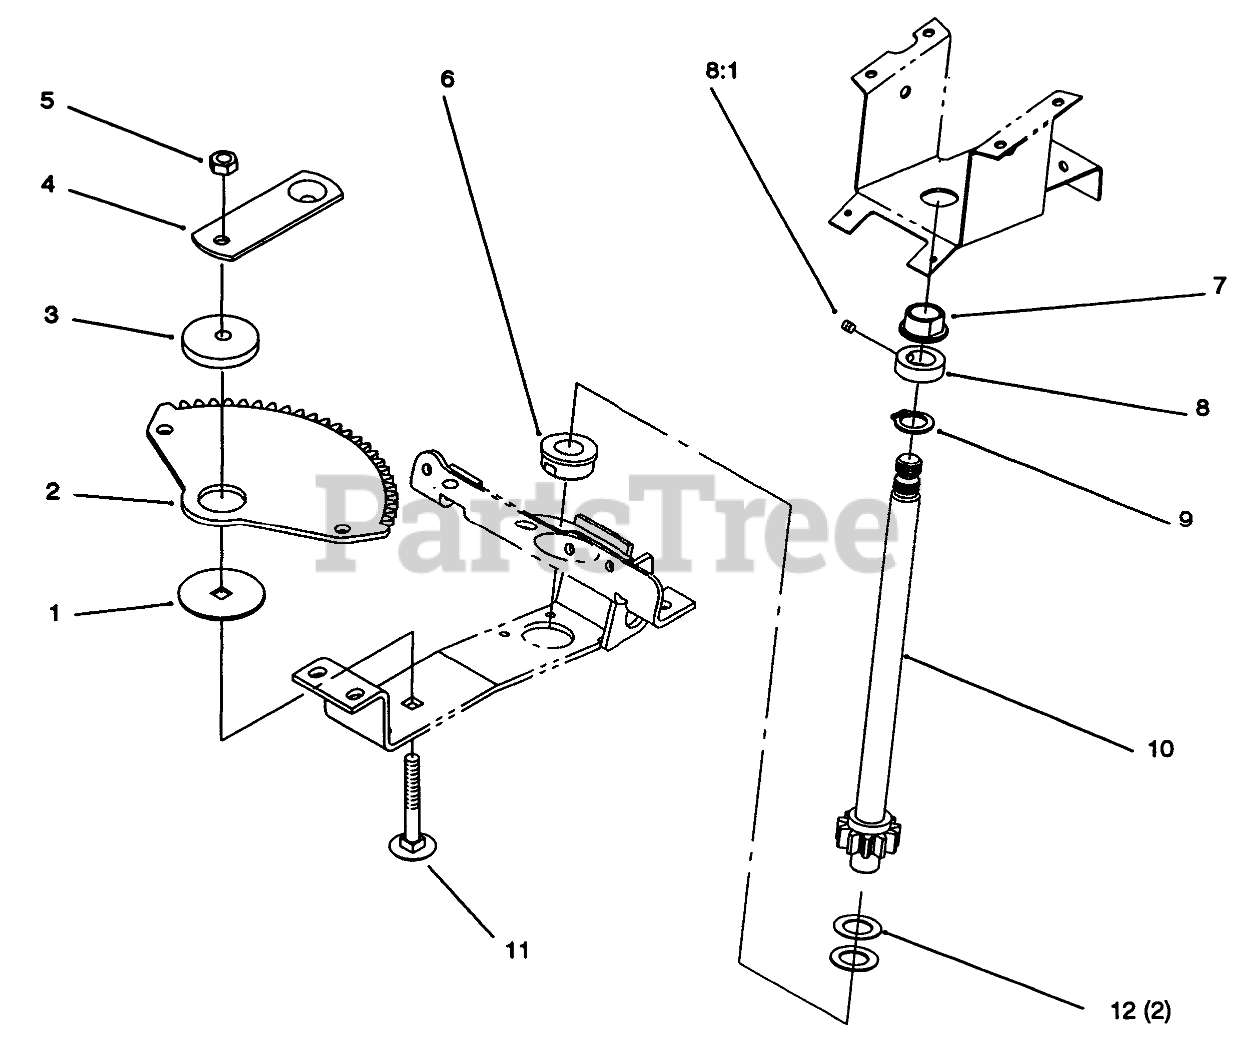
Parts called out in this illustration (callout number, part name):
1	WASHER-BEARING
2	GEAR-SECTOR
3	BUSHING
6	BEARING-WHEEL
7	BEARING-FLANGED
8	COLLAR
8:1	SCREW-HSH
9	RING-RETAINING
10	SHAFT-STEERING, LOWER
11	SCREW-CARR
12	WASHER
